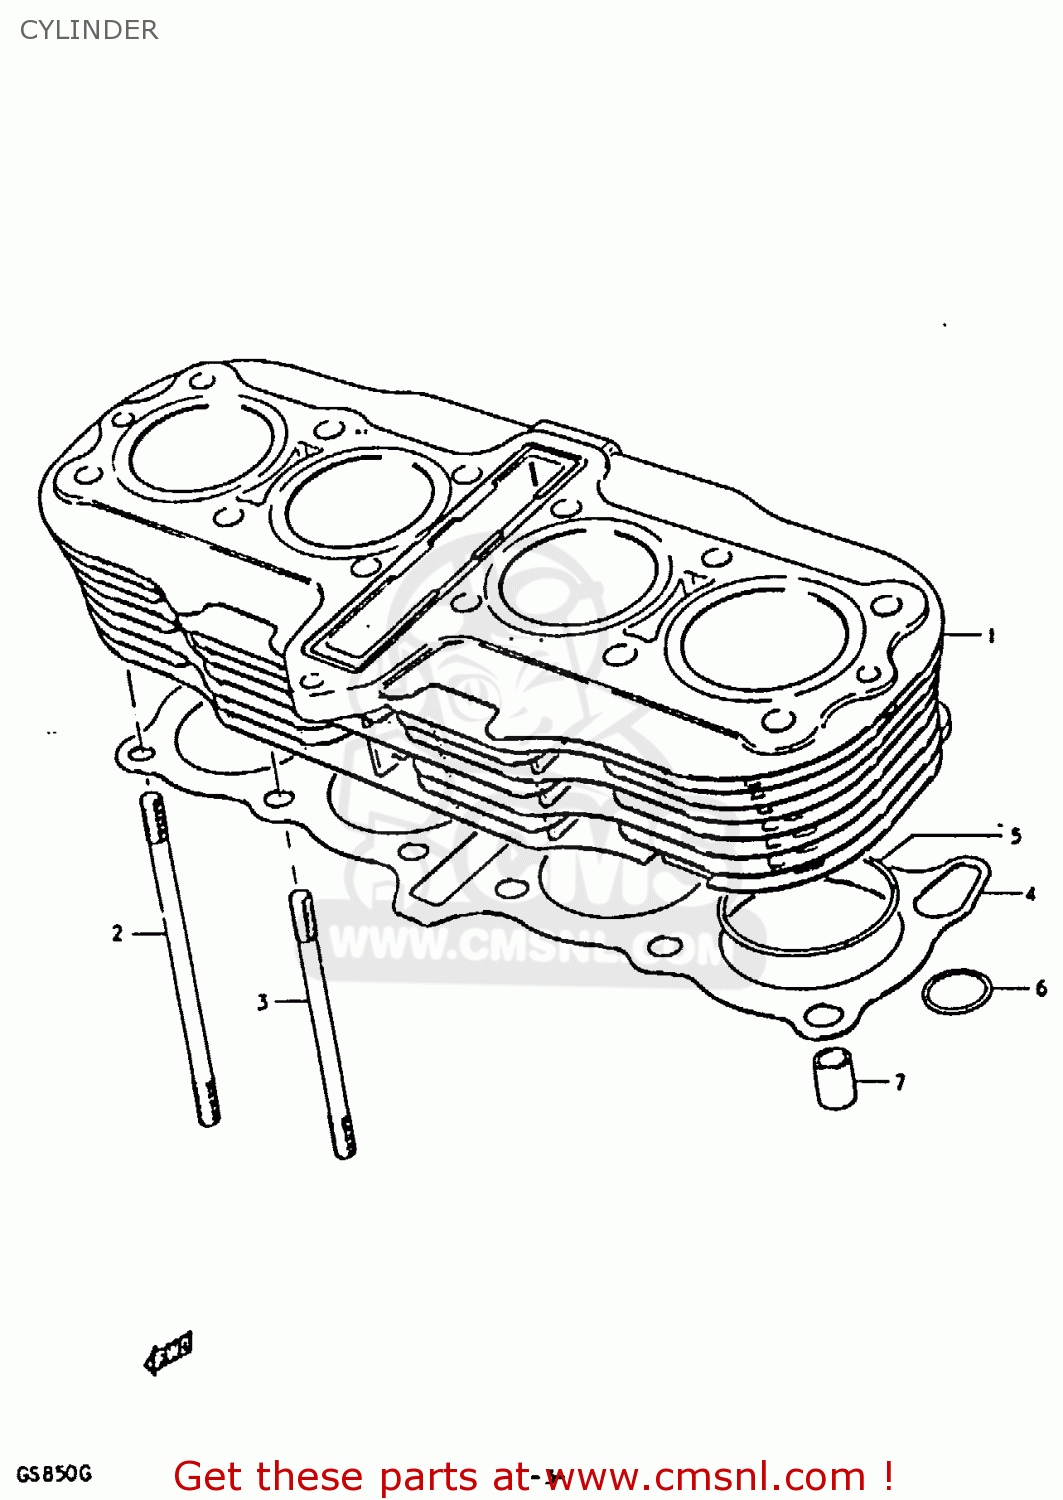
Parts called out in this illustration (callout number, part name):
1	CYLINDER
2	BOLT,STUD
3	STUD
4	GASKET,CYLINDER (MCA)
5	O RING(D:2,ID:70)
6	O RING(D:3.05)
7	PIN
